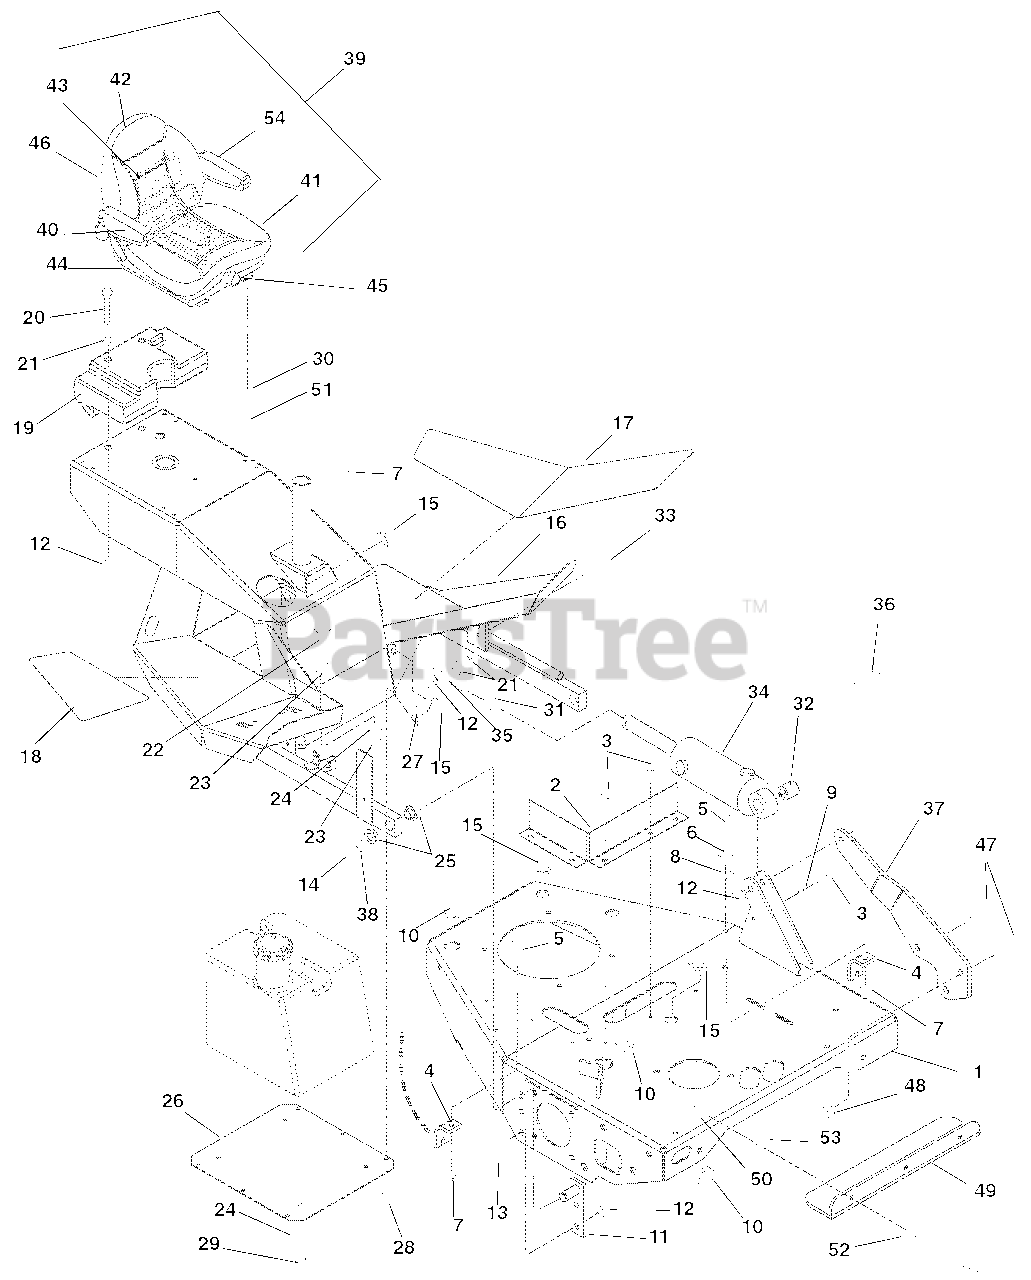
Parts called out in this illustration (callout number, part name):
1	Weldment, Frame
2	Heat Shield
3	Screw, Tapping .25-20 x .50 Hex Washer Head
4	Bracket, Cable
5	Bolt, Hex .31-18 x 1.00 Grade 5
6	Washer, Flat Steel .344 x .688 x .065
7	Nut, Locking Top Flange .31-18
9	Clamp, Steel 1.0
10	Grommet 1.25
11	Weldment, Pivot
12	Nut, Locking-Top-Flange .50-13
13	Bolt, Hex .50-13 x 1.50 Grade 5
14	Ring, Retaining-External .689 x .077
15	Grommet .75 x 1.06 x 1.38
16	Weldment, Sulky
17	Pad, Left Hand Floorboard
18	Pad, Right Hand Floorboard
19	Weight, Rear
20	Bolt, Hex .50-13 x 4.00 Grade 5
21	Washer, Flat-Steel .531 x 1.06 x .095
22	Bolt, Round Head Square Neck .31-18 x 1.50 Grade 5
23	Nut, Hex .31-18
24	Washer-Locking .31 x .078
25	Bushing, Flange-Nylon .762 x 1.00 x .58 x 1.48
26	Plate, Bottom
27	Nut, Locking-Top-Flange .38-16
28	Bolt, Hex .38-16 x 1.00 Grade 5
29	Bolt, Hex .31-18 x .75 Grade 5
30	Bushing, Sleeve .377 x .624 x .235
31	Nut, Jam .50-20 Grade 2
32	Bushing, .516 x 1.00 x 1.05
33	Bolt, Hex .50-13 x 2.25 Grade 5
34	Cylinder, Platform Lift
35	Assembly, Rod End Right Hand
36	Bolt, Hex .50-13 x 2.75 Grade 5
37	Support, Cylinder Brace
38	Washer, Hardened Thrust .758 x 1.23 x .031
39	Seat, Suspension, Light Gray, Seat Bolt Bushing
40	Kit, Right Hand Armrest Assembly
41	Kit, Seat Cushion, Light Gray
42	Kit, Seatback Cushion, Light Gray
43	Kit, Spring and Saddle
44	Kit, Seat Slide
45	Kit, Seat Knob
46	Kit, Seat Back Panel
47	Bolt-Hex .62-11 x 1.75 Grade 5
48	Nut-Nylon Locking .625-11
49	Guard, Hose
50	Bolt, Round Head Square Neck .25-20 x .75
51	Nut, Push .312
52	Nut, Locking Top Flange .25-20
53	Nut, Push .250 x .50
54	Kit, Left Hand Armrest Assembly
